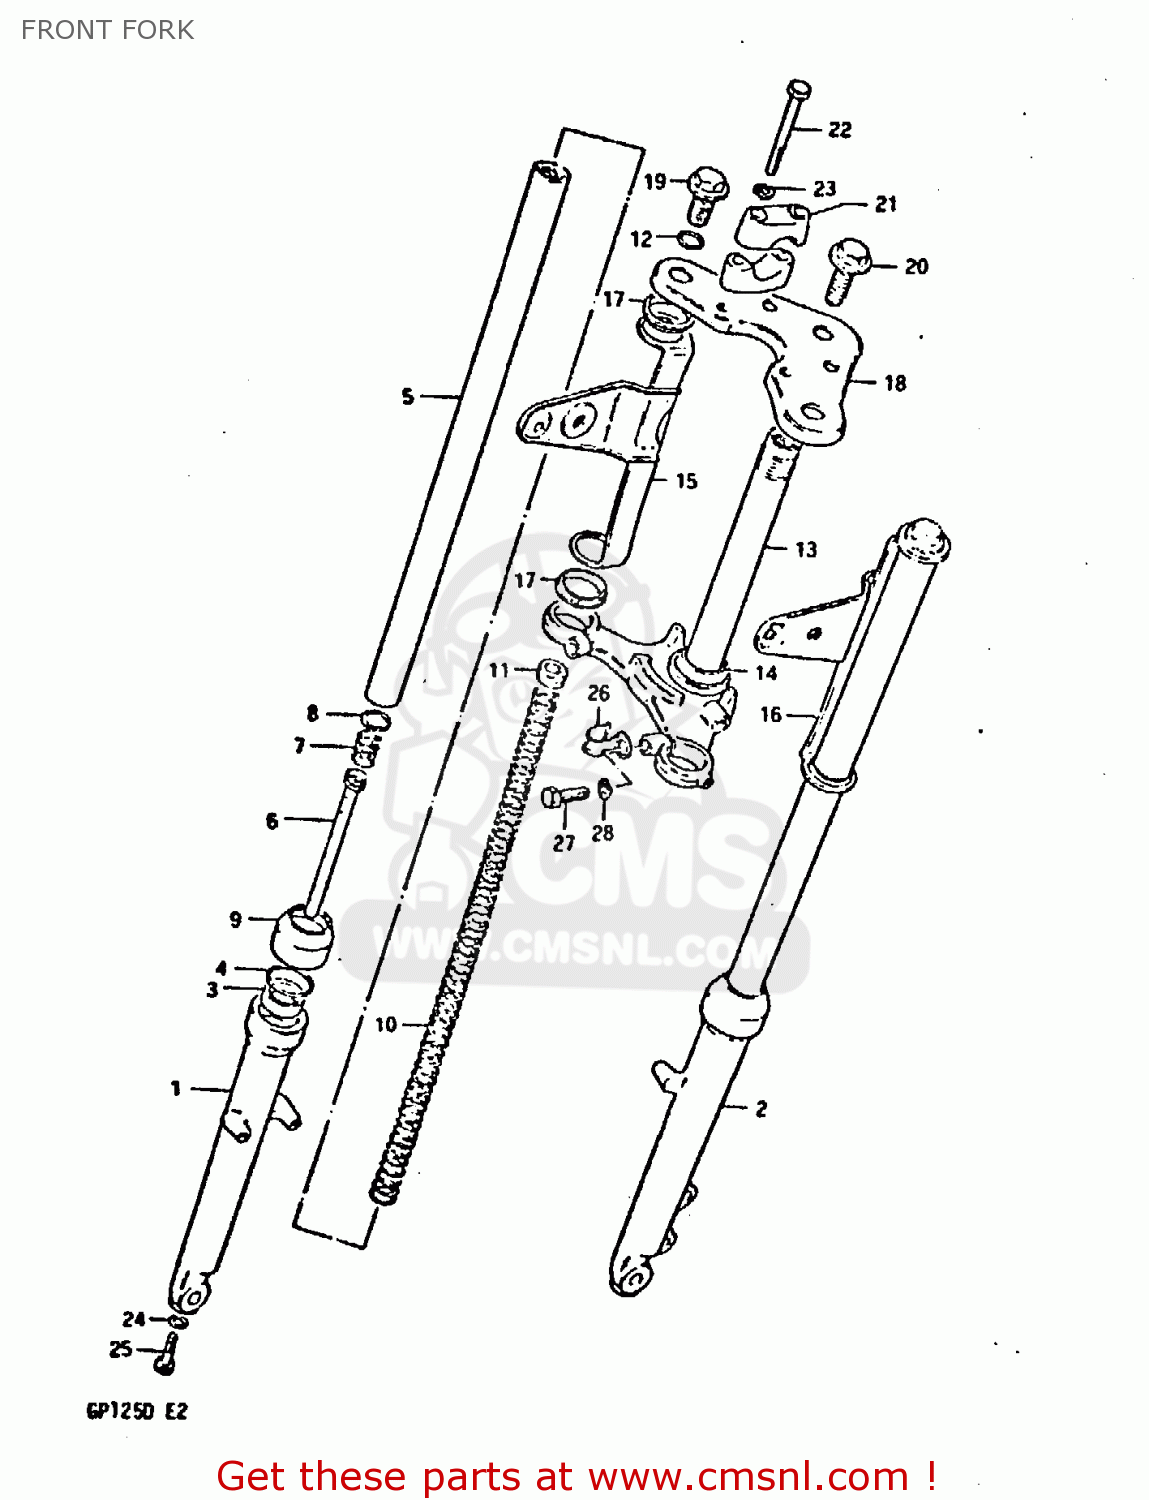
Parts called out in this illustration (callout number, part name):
1	OUTER TUBE, RH
2	OUTER TUBE, LH
3	SEAL,OIL
4	RING,SNAP
5	TUBE, INNER
6	CYLINDER
7	SPRING,REBOUND
8	RING
9	DUST SEAL
10	SPRING
11	NUT
12	O-RING,FORK INNER TUBE
13	STEM, STEERING
14	RACE,STEERING OUTER LWR
15	BRACKET, HEADLAMP RH (BLACK)
16	BRACKET, HEADLAMP LH (BLACK)
17	GASKET (NAS)
18	HEAD, STEERING STEM (BLACK)
19	CAP
20	BOLT
21	HOLDER,HANDLE(BLACK)
22	BOLT
23	LOCK WASHER
24	GASKET (NAS)
25	BOLT,FORK CYLINDER(10X25)
26	CLIP,SPEEDOMETER CABLE
27	BOLT 10X30
28	LOCK WASHER
